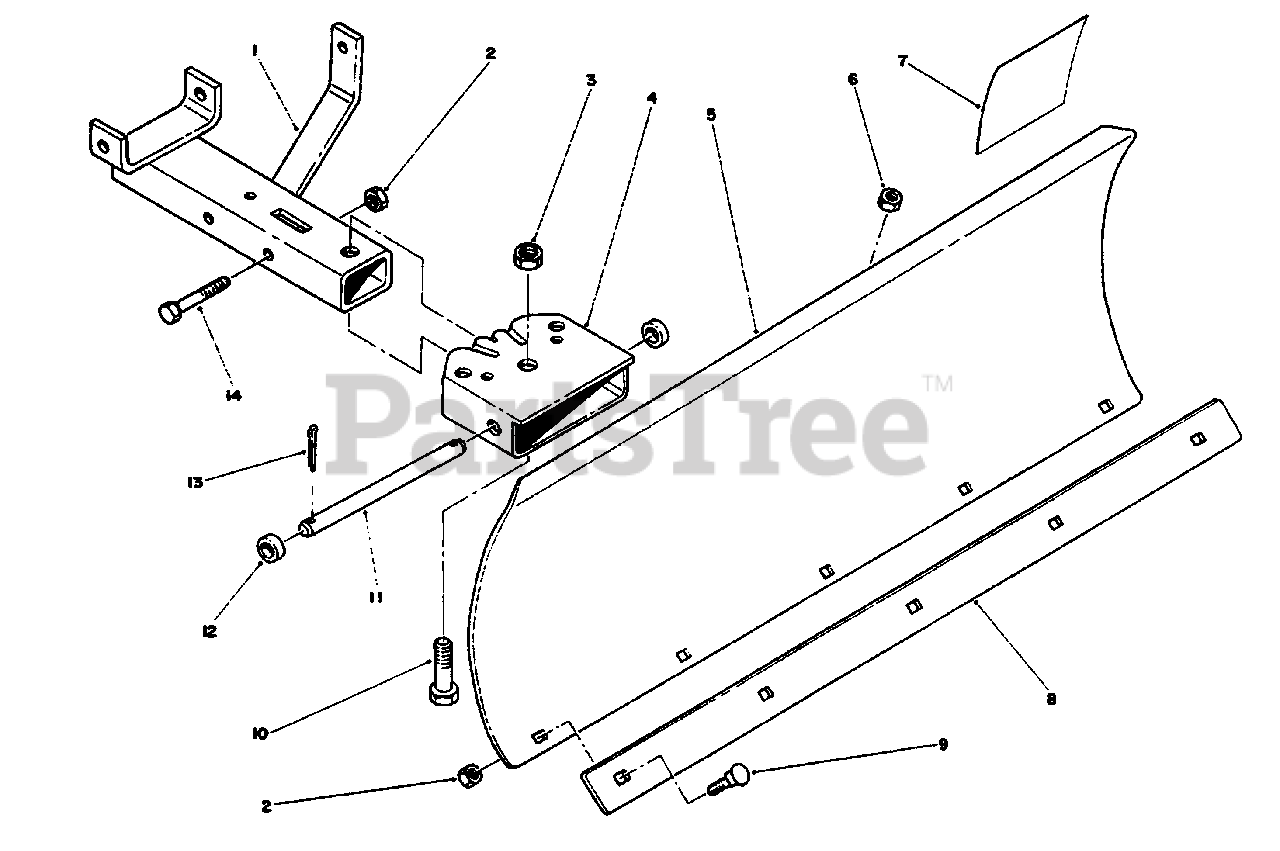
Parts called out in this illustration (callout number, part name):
2	Nut-Lock
3	Nut-Lock
4	Quadrant
5	Blade
6	Nut-Jam
7	Decal-Danger
8	Plate
9	Bolt-Carriage
10	Screw-Hex Hd. Cap
11	Rod-Lower Pivot
12	Spacer
13	Pin-Cotter
14	Screw-Hex Hd. Cap
